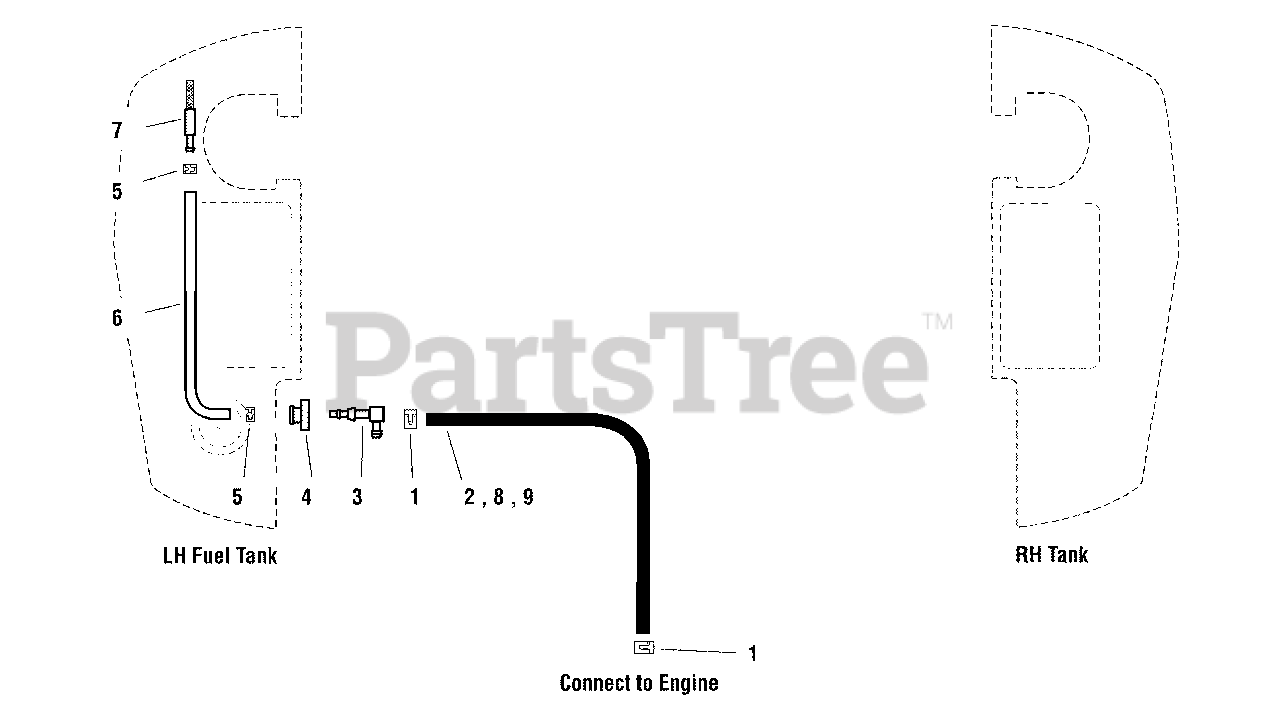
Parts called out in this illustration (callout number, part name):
1	CLAMP, HOSE, EXTERNAL, 1/2 - RED
2	HOSE, 1/4" FUEL, 16.00"
4	BUSHING-FUEL TANK RED RUBBER (SV)
6	HOSE ASSEMBLY
8	HOSE, 1/4" FUEL, 10.00"
9	HOSE, 1/4" FUEL, 8.00"
